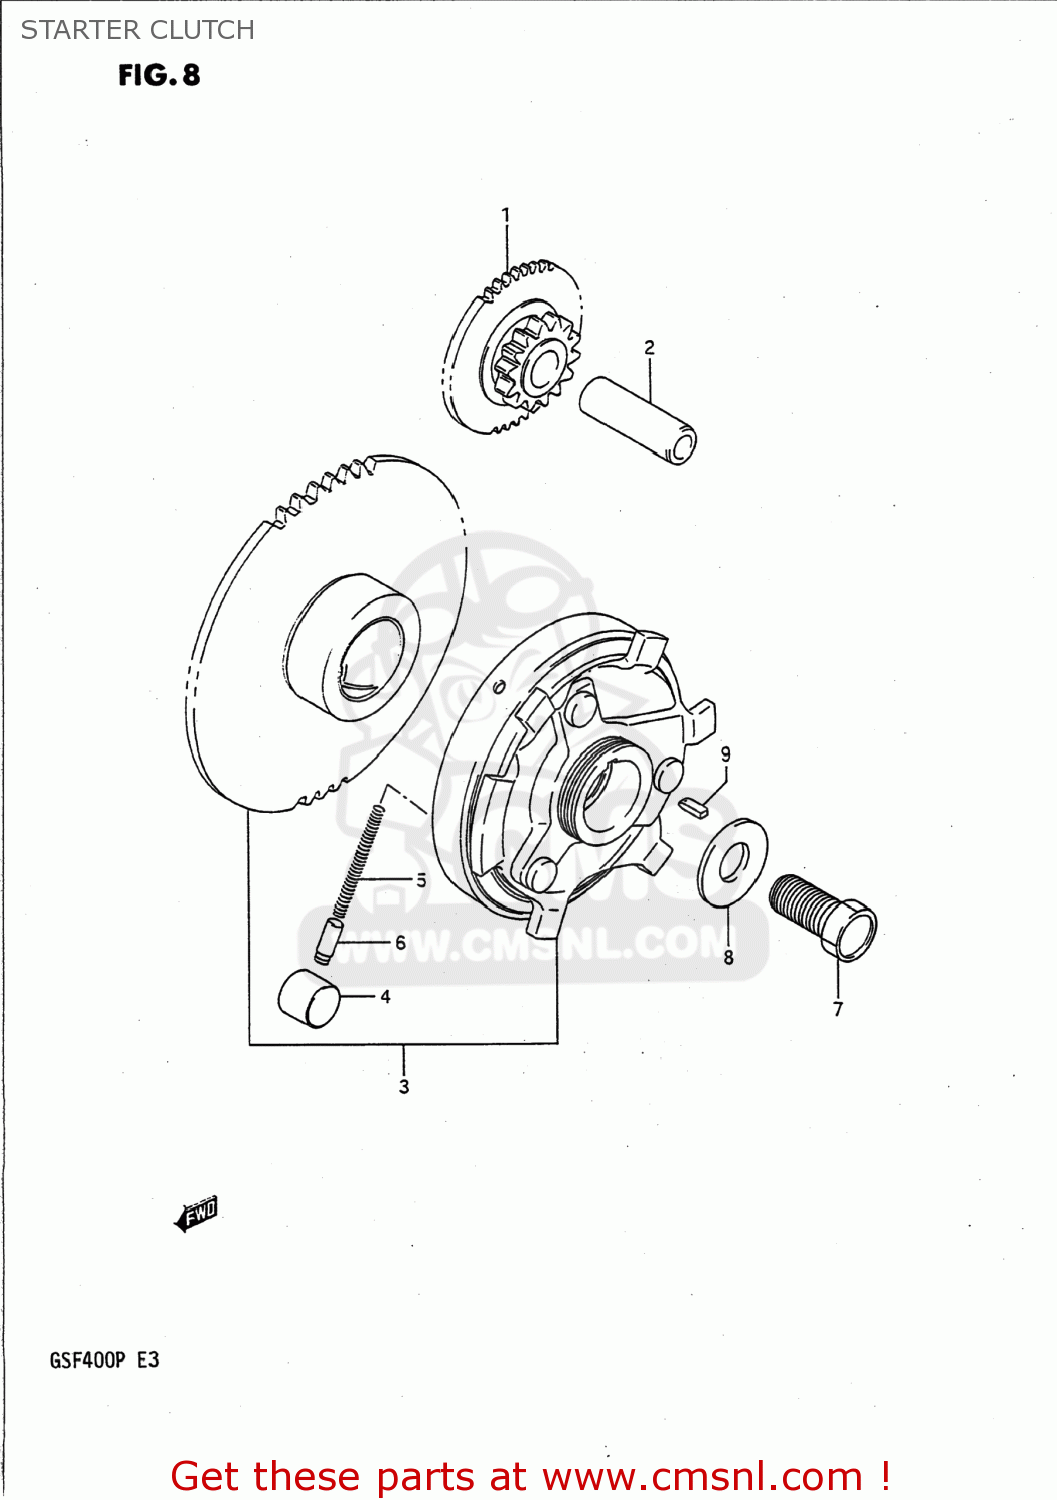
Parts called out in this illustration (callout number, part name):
1	GEAR,STARTER IDLE
2	PIN(7.4X13X40)
3	CLUTCH SET,STARTER
4	ROLLER(15X13)
5	SPRING
6	PIECE,PUSH
7	BOLT
8	WASHER(12X30X3)
9	KEY
